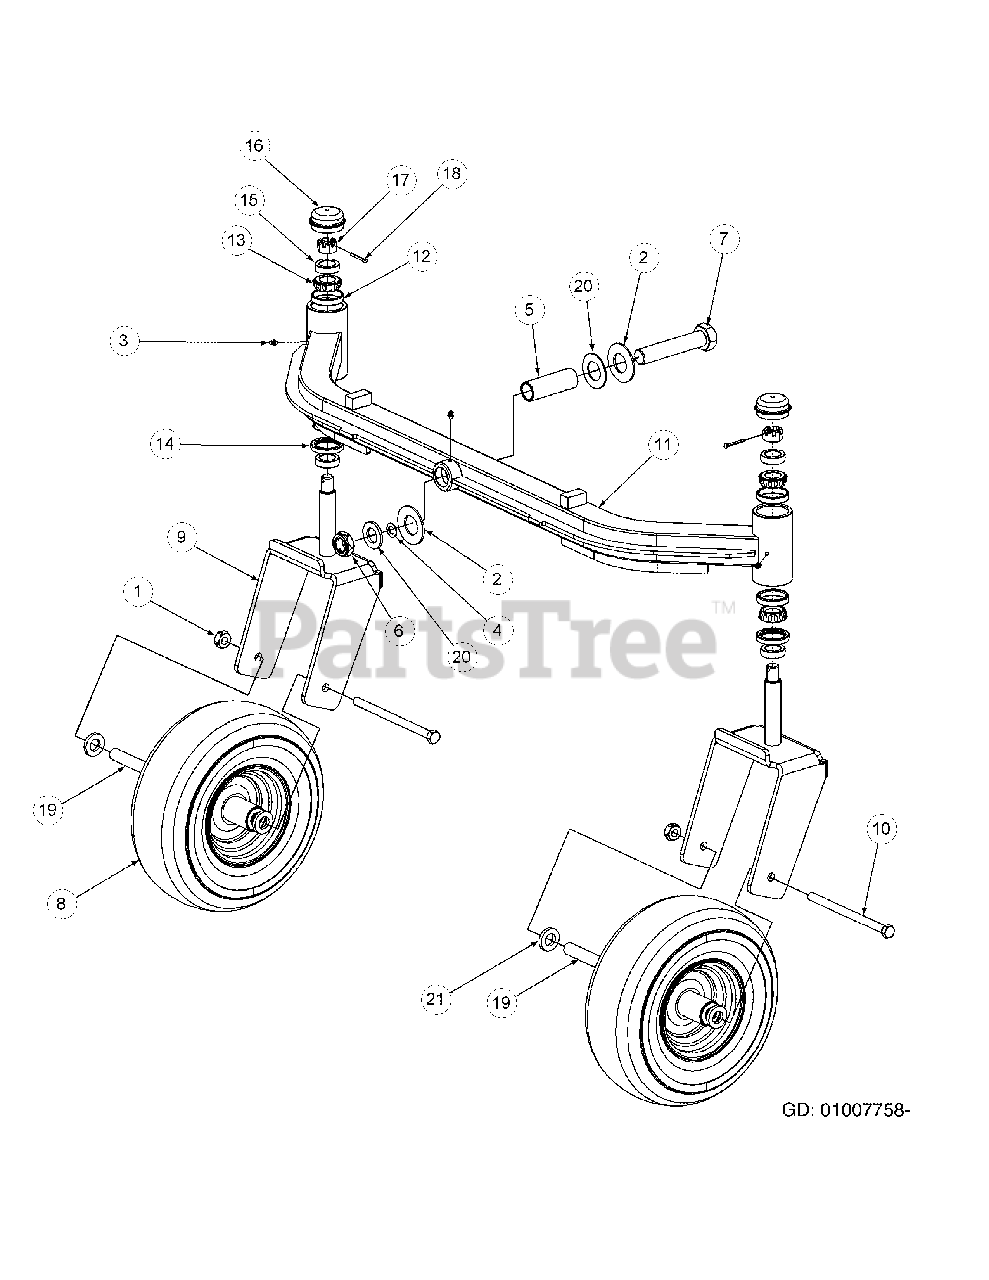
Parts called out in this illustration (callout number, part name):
1	Nut, 1/2-20, Center Lock
2	Bell Washer, 1.25 ID x 2.5 OD x .180
3	Grease Fitting
4	Retainer Extension, Self Locking
5	Spacer, 1.005 ID x 1.25 OD x 3.6
6	Nut, Jam, 1.0-14, Insert Lock
7	Hex Cap Screw, 1-14 x 5.0
8	Wheel, 13 x 6.50 x 6, White includes:
9	Yoke, Caster Wheel
10	HHCS, 1/2-20, 7.50
11	Front Axle Assembly
12	Cup Bearing
13	Bearing Cone
14	Seal
15	Ring Seal
16	Grease Cap, 1.986 OD
17	Slotted Nut, 3/4-16
18	Cotter Pin, 5/32, 1.25
19	Wheel Spacer
20	Flat Washer, 1.00 ID x 2.00 OD x .075
21	Spacer, .812 ID x .218LG
